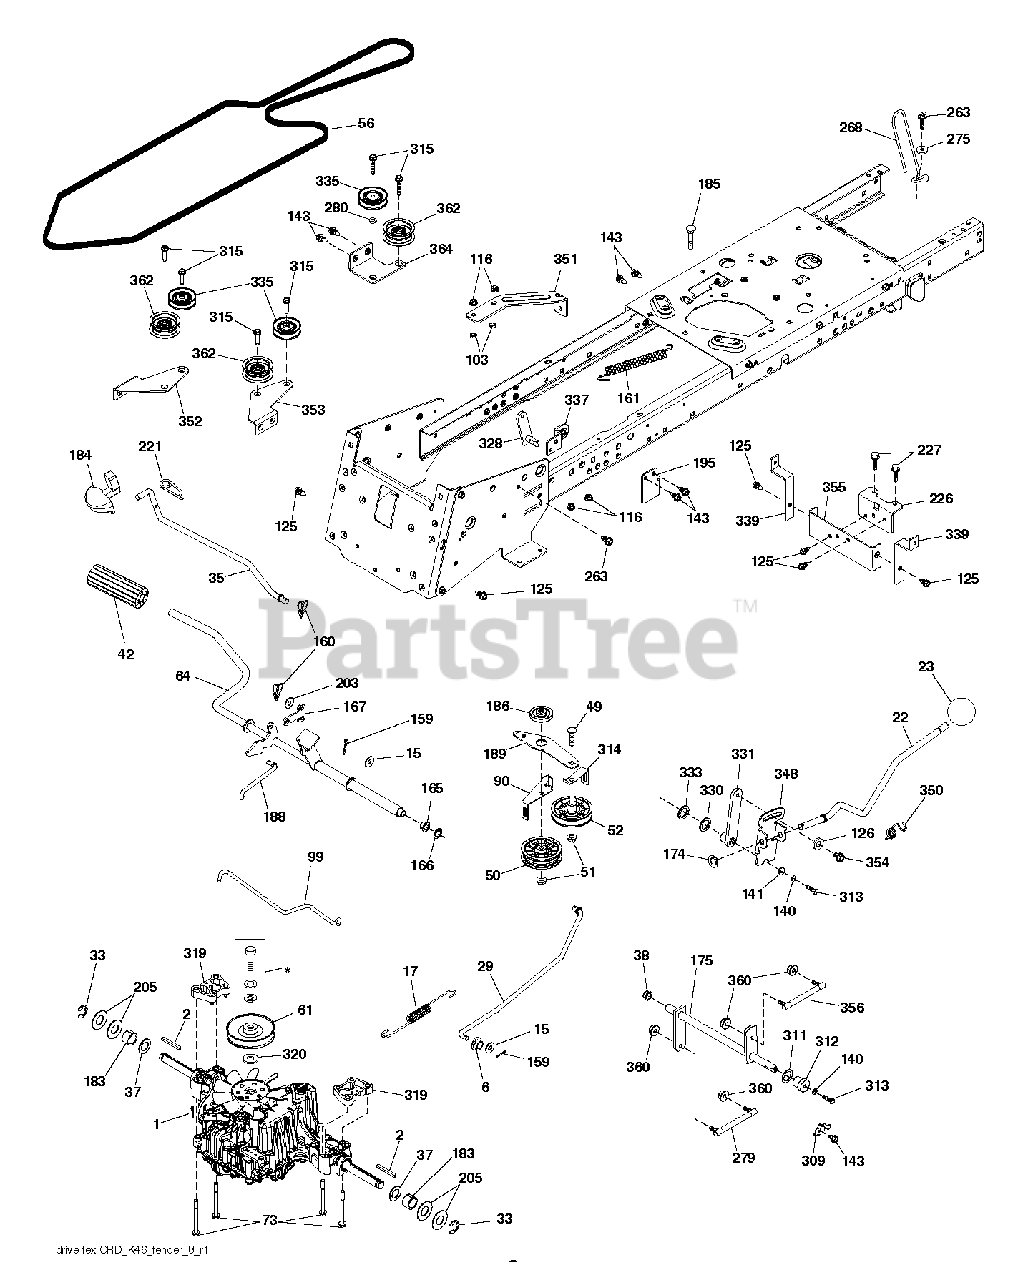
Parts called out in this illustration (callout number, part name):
6	MANDREL ASS'Y
17	Spring Brake
22	ROD ROD SHIFT FENDER
29	ROD
35	ROD, BRAKE, PARK
37	WASHER.HARDENED
38	NYLINER SNAP 5/8" ID
42	PEDAL COVER T
49	BOLT
50	IDLER.FLAT.910.OFFSET
51	NUT LOCK FLG 3/8-16 UNC
52	IDLER.V-GROOVE.910.OFFSET
56	V BELT DELV 113 K46 C
61	Transaxle Pulley
64	SHAFT.ASM.PEDAL.BRAKE.
90	KEEPER KEEPER BELT CL
99	ROD ROD BYPASS CRD TE
116	NUT LOCK HEX FLANGE 5/16-18
125	SCREW
126	WASHER.SRRTD.5/16
140	LOCKWASHER
141	WASHER LT
159	COTTER PIN
160	RETAINER CLIP
161	SPRING, RETURN LT
165	BUSHING.SHAFT.BRAKE.HAND
167	LATCH.BRAKE.SPRING
174	NUT.PUSH.500.2006
184	HANDLE.PARKING.BRK.PRED.LT.RED
186	SPACER.RETAINER
188	LINK.CLUTCH.GROUND.DRIVE
189	BELLCRANK BELLCRANK G
203	WASHER
221	RETAINER.SPRING.CLIP.H
226	BRACKET.MOUNT.TORQUE.K46.TLT
227	SCREW
263	SCREW, 3/8-16X3/4
275	WASHER
279	LINK SUBASM. LINK AND STUD
309	PLATE FASTENING LT
314	RETAINER KEEPER BELT
315	BOLT.5/16-18X1.25
319	SPACER SPACER TRANSAX
320	WASHER.SPACER.MANDREL
330	WASHER.NYL.7/8IDX.105"HYD CR
331	HUB HUB SHIFT FENDER
335	PULLEY.V-IDLER.
337	BRACKET BRACKET SUPT
339	STRAP STRAP TORQUE K4
348	ARM ARM CLEVIS ROD SH
350	TORSION SPRING SPRING
351	BRACKET BRACKET DECK
352	Idler Bracket
353	Bracket
355	STRAP STRAP TORQUE K4
360	NUT NUT HEX CENTERLOC
362	IDLER.FLAT.2.25.INCH
364	BRACKET BRACKET IDLER
